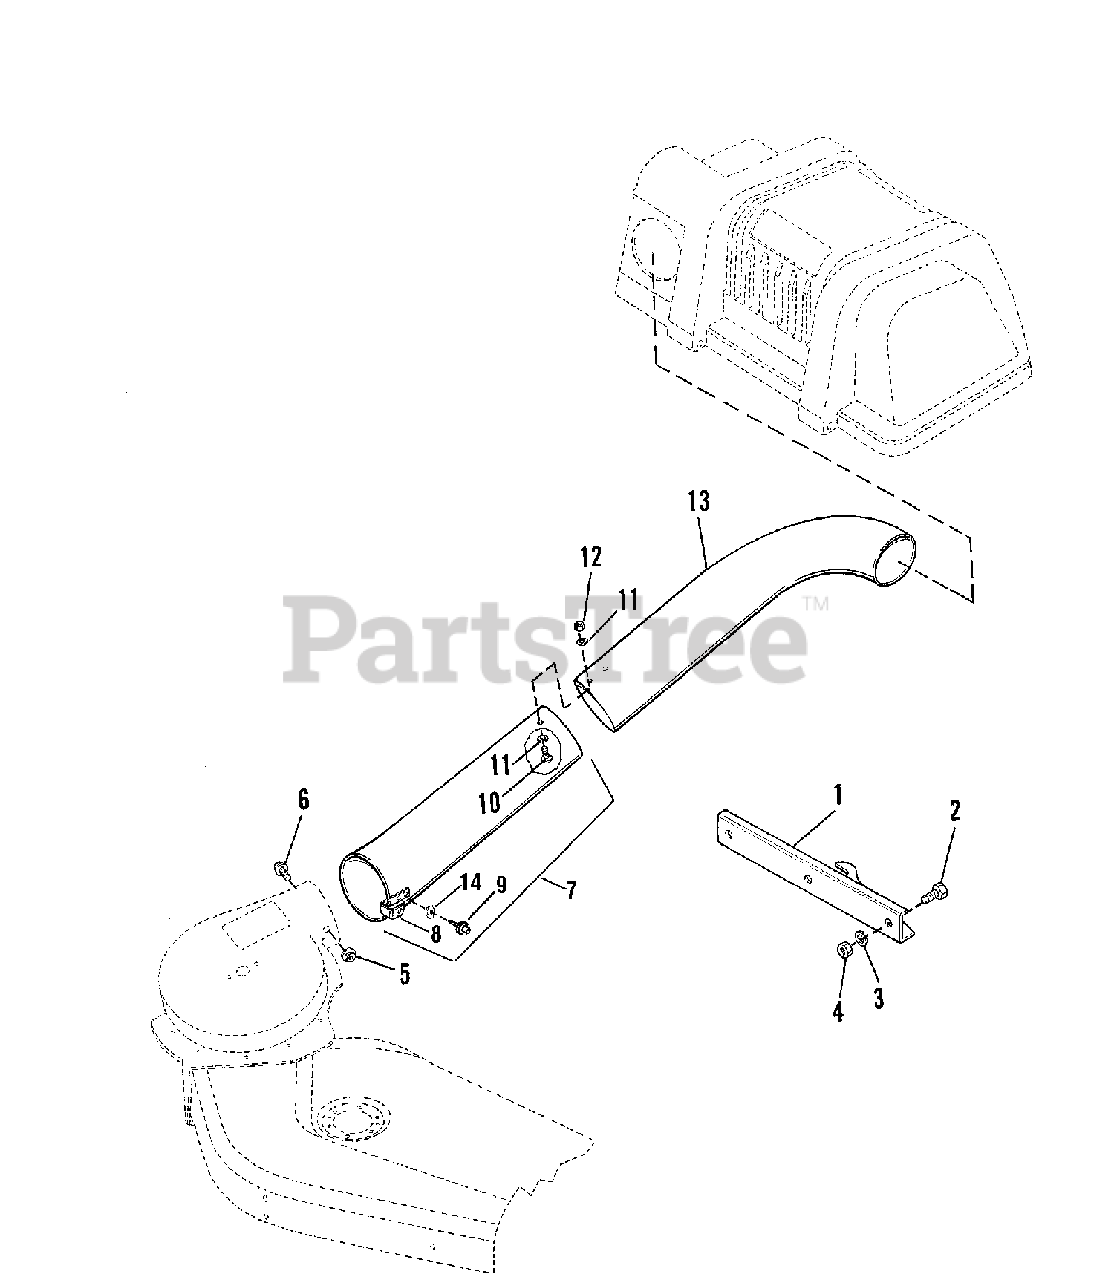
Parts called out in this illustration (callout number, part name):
2	CAPSCREW, Hex Head, 3/8-16 x 1
3	LOCKWASHER, 3/8
4	NUT, Hex, 3/8-16
5	NUT, Hex Flange Lock, 1/4-20
6	CARRIAGE BOLT, 1/4-20 x 5/8
7	TUBE ASSEMBLY, Lower (Inc. Ref. Nos. 8, 9, & 14)
8	CLIP, Spring
10	SCREW, Truss Head, #10-32 x 1/2
11	WASHER, #10
12	NUT, Hex, Washer Assembly, #10-32
13	TUBE, Upper
